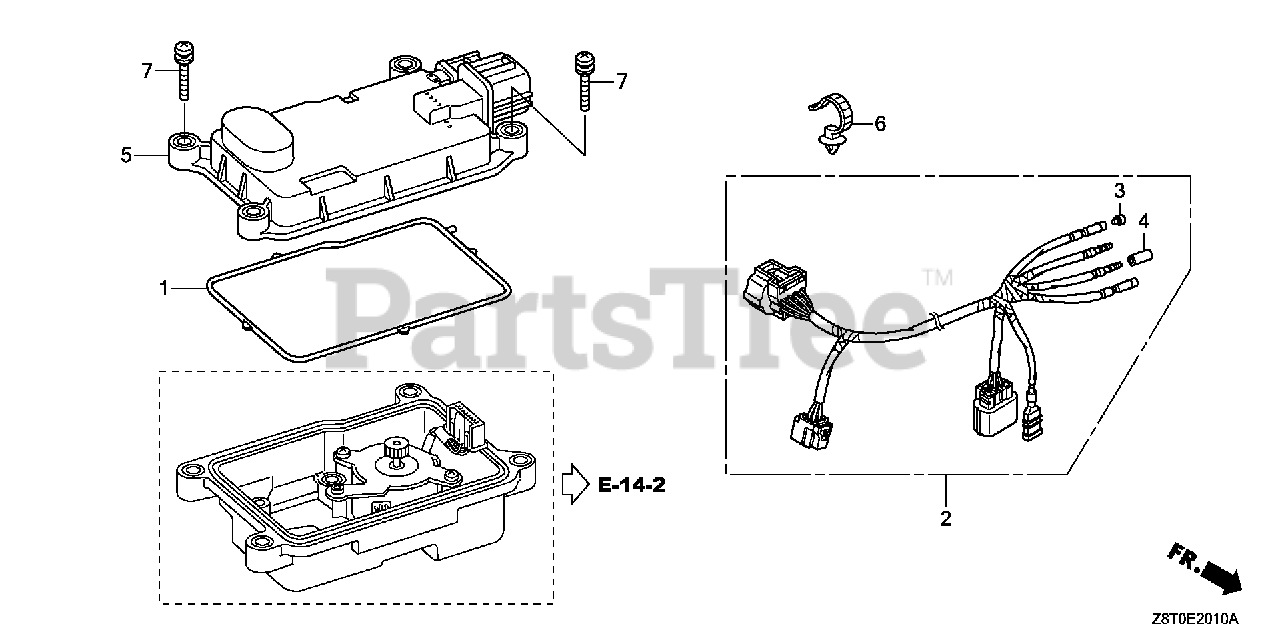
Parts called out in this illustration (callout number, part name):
1	SEAL, ELECTRONIC CONTROL UNIT COVER
2	WIRE HARNESS ASSY., ENGINE
3	PLUG, CONNECTOR (INNER)
4	PLUG, CONNECTOR (OUTER)
5	CONTROL UNIT, ELECTRONIC
6	CLIP, HARNESS BAND (145MM) (BLACK)
7	SCREW-WASHER (4X20)
